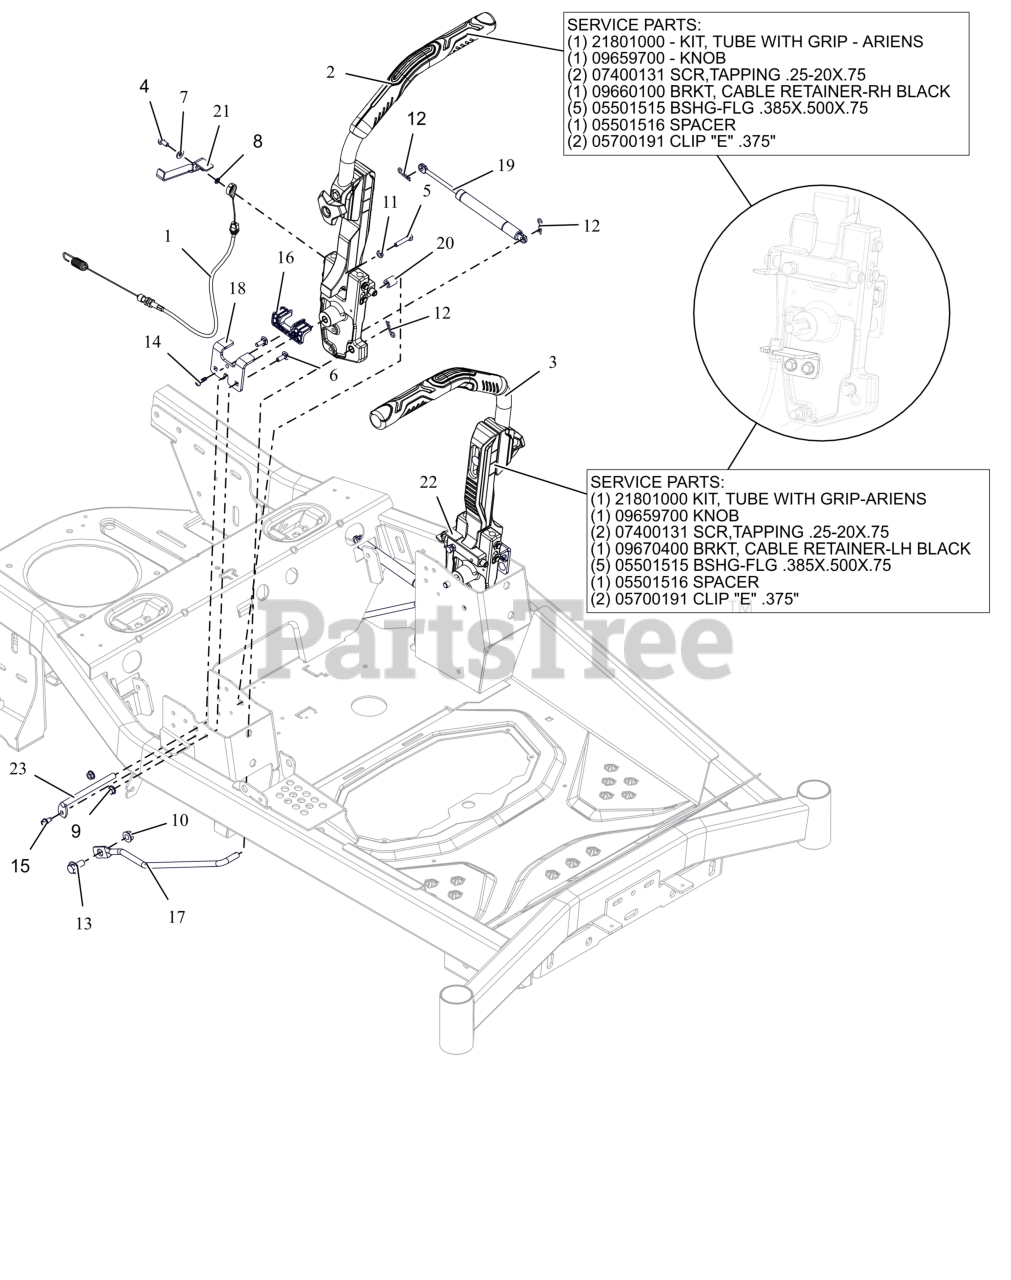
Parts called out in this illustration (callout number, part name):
1	CABLE- PARK BRAKE
2	ASM- CONTROLS -RH
2	KIT - TUBE WITH GRIP - ARIENS
2	KNOB, STEERING ADJUSTMENT
2	SCR,TAP .25-20X.75 HWH TR ZCC
2	BRKT, CABLE RETAINER -RH BLACK
2	BSHG-FLG .385X500X.75
2	SPACER
2	3/8" E RETAINING RING EXTERNAL
3	ASM- CONTROLS -LH
3	KIT - TUBE WITH GRIP - ARIENS
3	KNOB, STEERING ADJUSTMENT
3	SCR,TAP .25-20X.75 HWH TR ZCC
3	BRKT, CABLE RETAINER-LH BLACK
3	BSHG-FLG .385X500X.75
3	SPACER
3	3/8" E RETAINING RING EXTERNAL
4	BLT, HEX .25-20X.50 G5ZCC EP80
5	BLT, HEX 0.25-20X1.25F GR5 ZCC
6	BLT, RHSN .25-20X.750 G5 ZCC
7	WSHR,FLT .281X.625X.065 ZCC
8	WSHR-FL-STL 0.25X0.406X0.05 ZCC
9	NUT-LK-CTR-FLG .25-20 ZC120
10	NUT-LK-CTR-FLG .375-16 GF ZCC
11	NUT-JAM .250-20 G2 ZCC
12	PIN, HAIR #213 .08X1.19 ZCC
13	BLT-SHLDR .50X.175 ZCC
14	SCR-TAP 12-14X.75PLSTITE @BLZC
15	SCR-TAP .25-20X.50 HWH ZCC
16	STEERING-PLASTIC LINER
17	WIREFORM- STEERING LINKAGE
18	PLATE- BRAKE STOP
19	DAMPER- STRAIGHT MOUNT
20	SPCR- SNAP-ON 1/2 X 1 1/2
21	BRKT, PARKING BRK ENG R (BLACK)
22	BRKT, PARKING BRK ENG L (BLACK)
23	PIN- FIXED STEERING PIVOT
